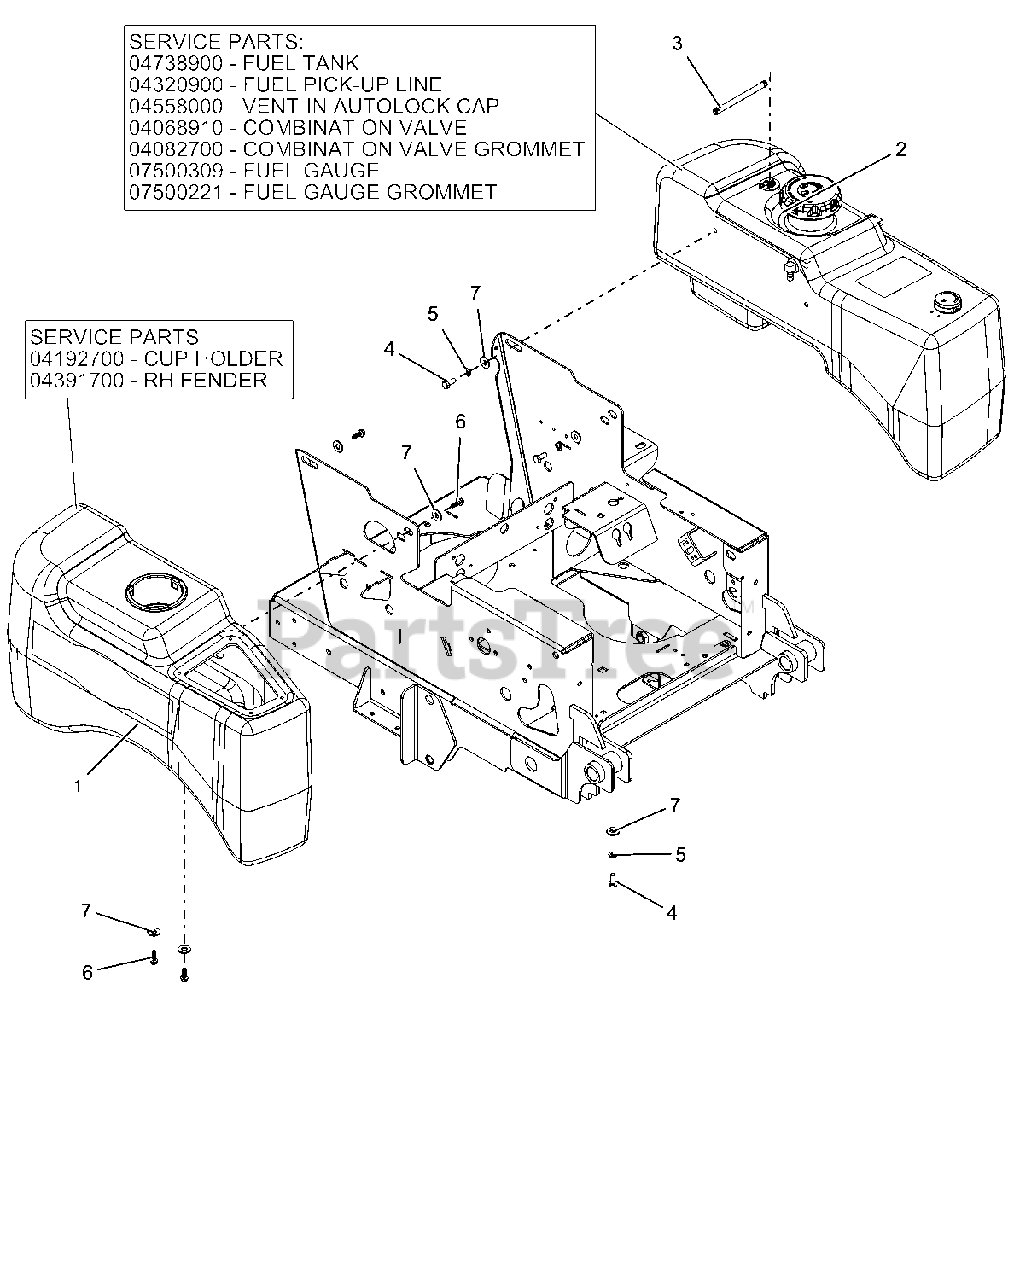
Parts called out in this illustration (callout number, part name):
1	CUPHOLDER, SNAP-IN 3.75OD
1	FENDER, RH
1	ASM, FENDER W/CUPHOLDER
2	ASM, FUEL PICK-UP SML/MED TANK
2	GROMMET, REMOTE VENT NITRILE
2	VALVE, COMBINATION
2	CAP, FUEL VENTIN AUTOLOCK
2	HD, FUEL TANK ASSEMBLY
2	TANK, LH FUEL
2	GAUGE, REMOTE FUEL SEALED 10"
2	GROMMET, FUEL GAUGE
3	ASM, VENT LINE - MAX ZOOM
4	@BLT-HEX .31-18X.75 GR5 YWZC
5	@WSHR-LK .31X.078 REG YWZC
6	SCR-PLASTITE .25-10X.75, YWZC
7	@WSHR-FL-STL.38X.875X.083 YWZC
